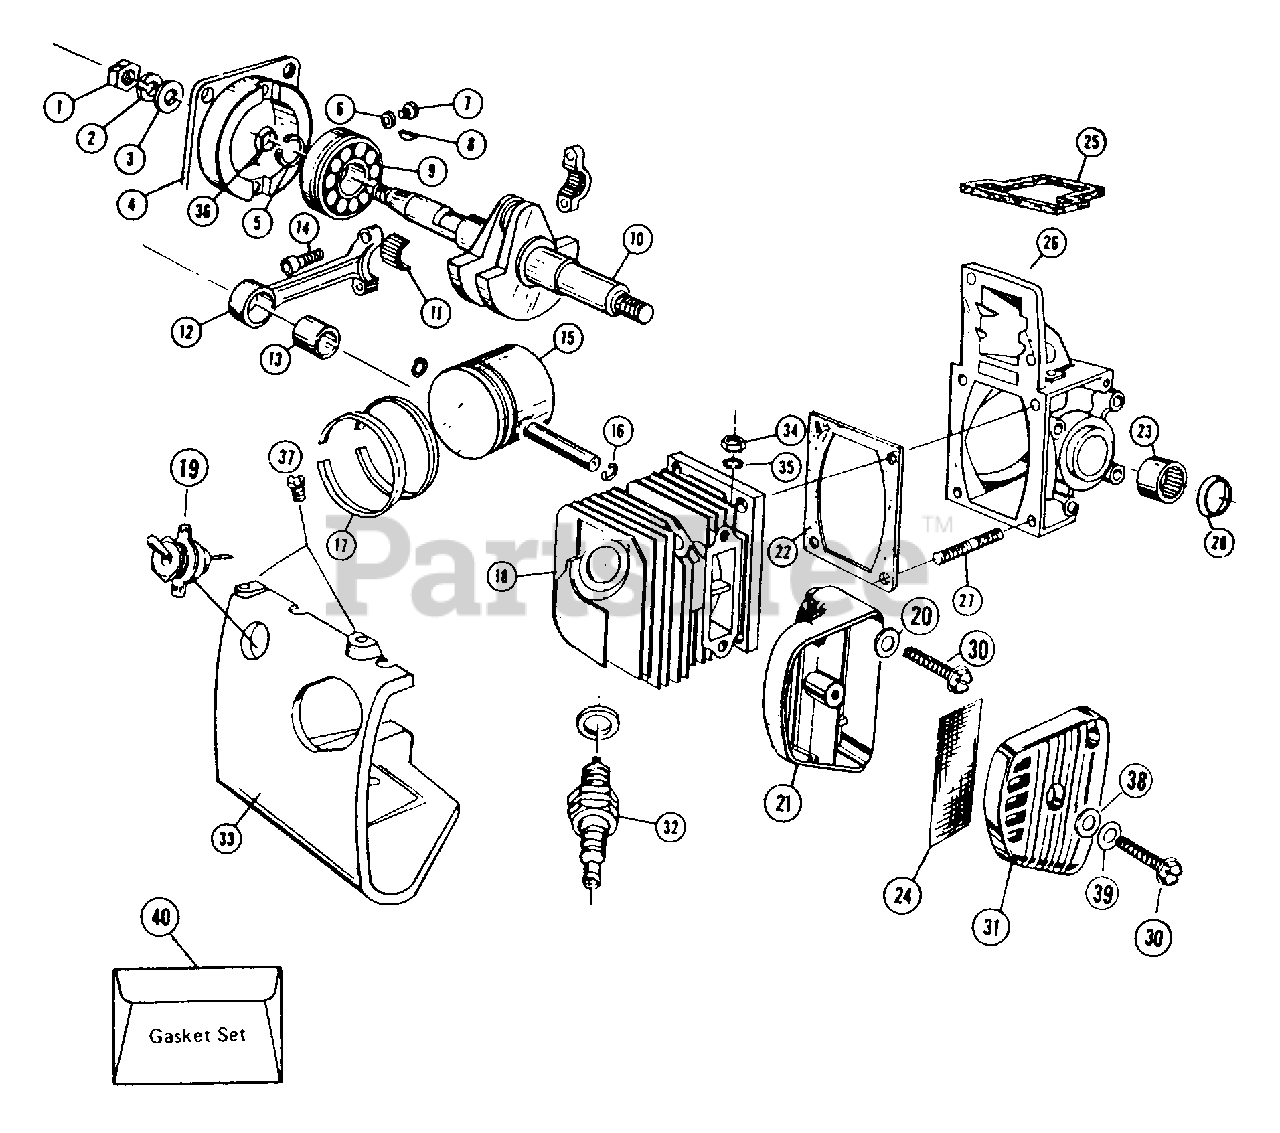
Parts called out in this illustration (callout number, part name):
1	Nut - Crankshaft
2	Washer - Lock
3	Washer - Flat
4	Bearing Carrier
5	Ring Retaining
8	Key Flywheel
10	Crankshaft
12	Connecting Rod Ass'y.
13	Bearing - Wrist Pin
14	Screw 8-36 x 1/2 Socket Head
15	Piston & Pin
16	Lock Ring
17	Piston Rings
18	Cylinder
19	Switch- Plate and Nut
20	Washer - Muffler
21	Body - Muffler
22	Gasket - Cylinder
24	Screen - Muffler
25	Dust Seal
26	Crankcase Assembly -
27	Stud - Cylinder
28	Seal
30	Screw - Muffler
31	Cover - Muffler
32	Spark Plug & Gasket
33	Shroud - Cylinder
34	Nut - Cylinder
35	Washer - Lock
36	Seal - Bearing Carrier
37	Screw- Cylinder Shroud
38	Washer - Flat - Heavy
39	Washer - Ramp Conical
40	Gasket Kit
